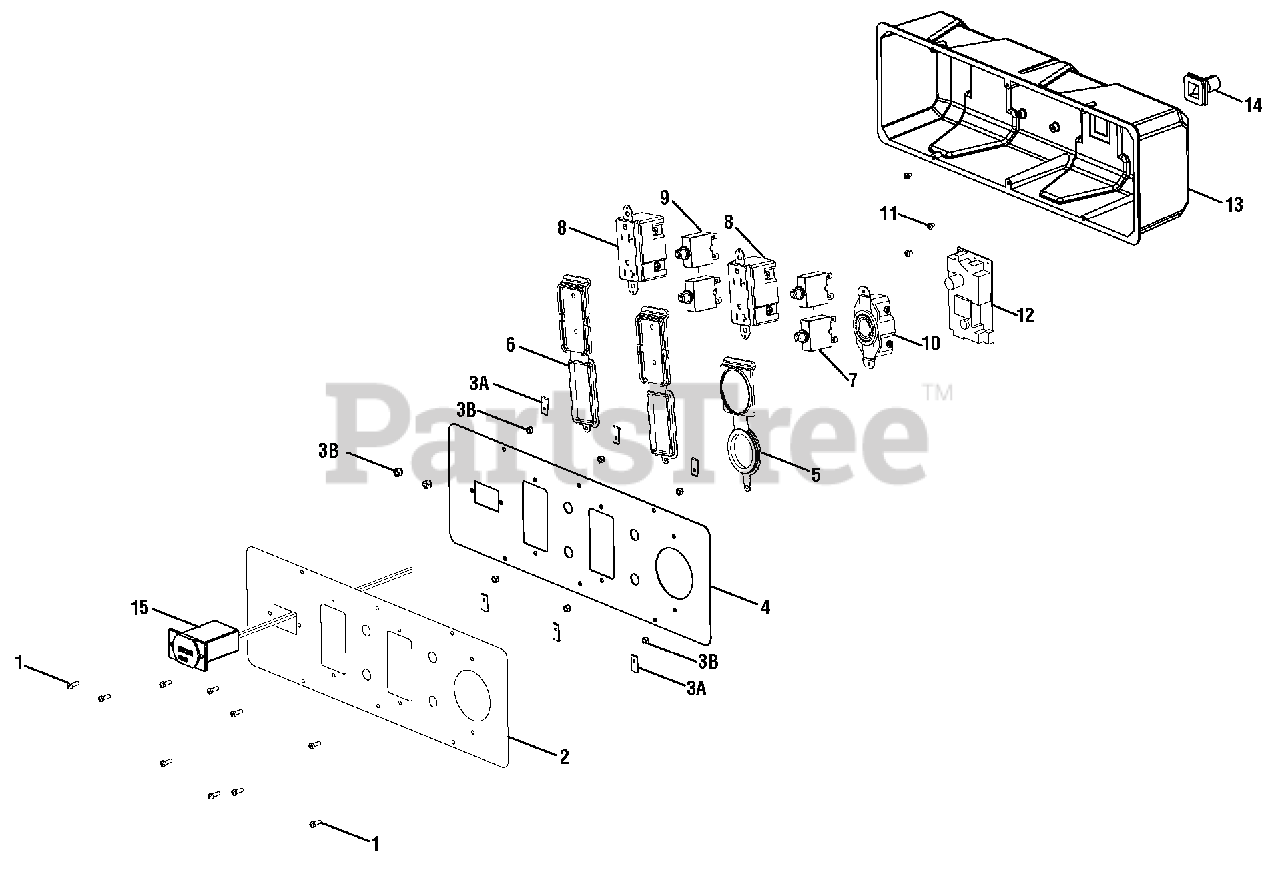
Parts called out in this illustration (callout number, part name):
1	Screw (6-20 x 3/8 in.)
2	Outlet Panel Label
3	U- Clip Nut (#6)
4	Front Panel
5	240 Volt Outlet Covers
6	120 Volt Outlet Covers
7	Circuit Breaker (30 Amp)
8	120 Volt Duplex Receptacle
9	Circuit Breaker (20 Amp, 125 Volt)
10	Twist Lock Receptacle (120/240 Volt, 30 Amp, L14-30R)
11	Screw (M3 x 5 mm,)
12	Battery Charger
13	Control Box (Back Panel)
14	Rubber Boot (Control Panel Assembly)
15	Hour Meter
